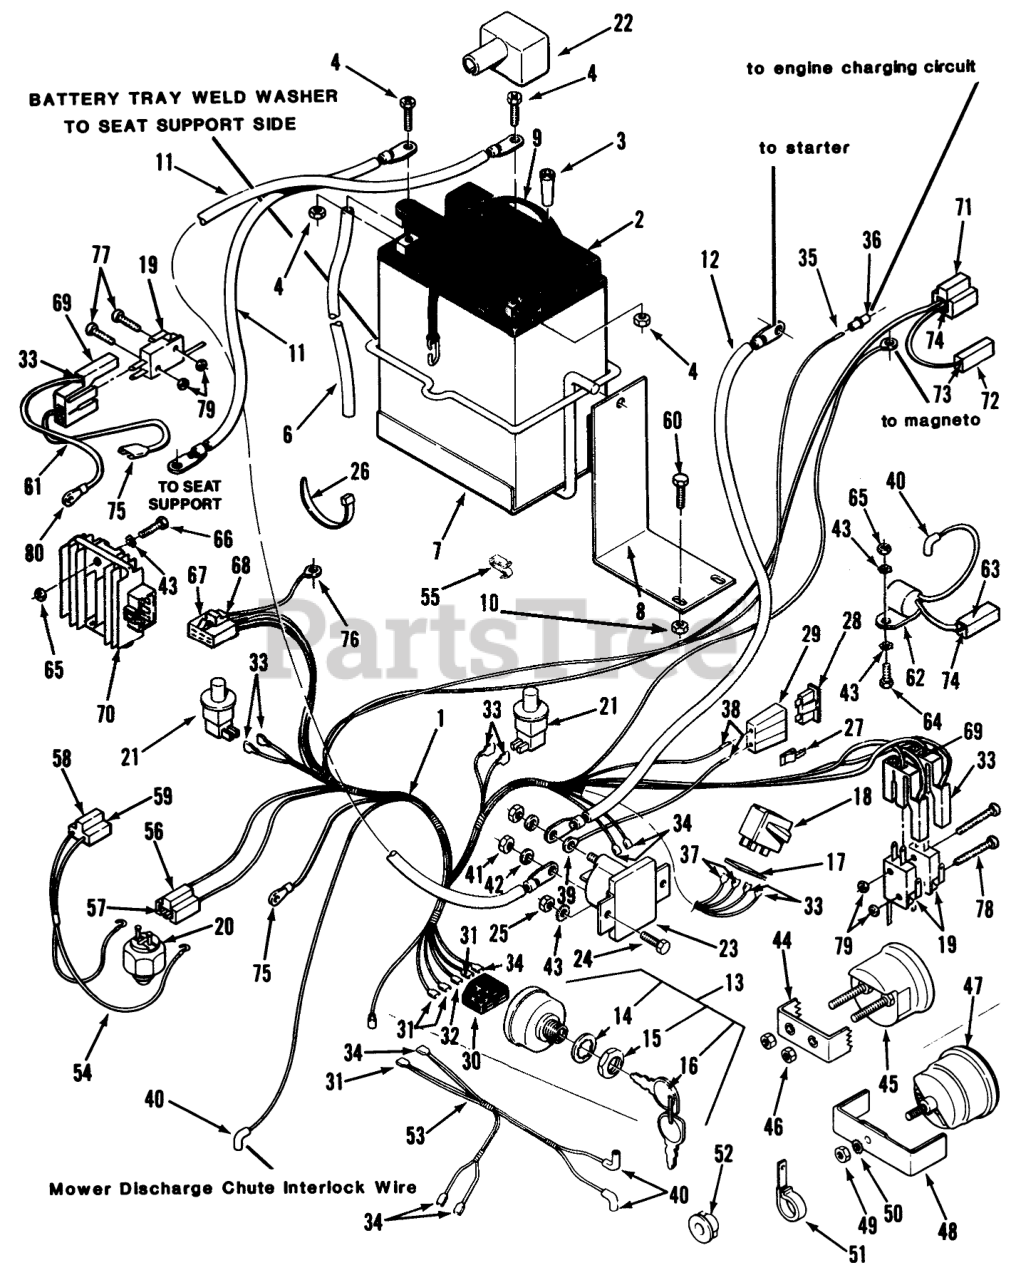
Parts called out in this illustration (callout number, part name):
1	WIRING HARNESS
2	BATTERY 120CCA
3	ADAPTER
4	ASSY BATTERY HDW
6	HOSE BATTERY DRAIN
7	BATTERY TRAY B
8	BRACKET B
9	STRAP
10	Nut
11	ASSY WIRE
12	WIRE ASM
13	Ignition Switch (includes items 14 & 15)
14	LOCKWASHER
16	Ignition Key
17	SHIELD-DIRT (DPDT)
18	PTO Interlock Switch w/item 17
19	SWITCH
20	SWITCH (N.C.-TRANS)
21	SWITCH (N.C.)
22	COVER-TERMINAL
23	Solenoid
24	Screw
25	Nut
26	PLASTIC TIE
28	FUSE-BLADE, 15 AMP
29	AUTO-FUSEBLOCK TERM
30	CONNECTOR-5 WAY-SERV
31	Terminal
32	Wire Terminal (Part of 1)
33	Wire Terminal (Part of 1)
34	Connector .250 x .032
35	Terminal
36	SOCKET HOUSING
37	Wire Terminal (Part of 1)
38	TERMINAL-FUSE
39	Wire Terminal (Part of 1)
40	Terminal Part of 5
41	Nut
42	Washer
43	LOCKWASHER
44	CLAMP MOUNTING
45	Voltmeter (includes items 44 & 46) 108-5 111-5, 111-6 & 112-C
46	HEX NUT 10-32 E.S.
47	Hourmeter (includes items 48, 49 50 & 51) 111-6 & 112-C
48	HOUR METER CLAMP
49	Hex Nut
50	Lockwasher
51	CLAMP
52	BUSHING-NYLON .75
53	Volt & Hourmeter Harness
54	ASSY WIRING HARNESS
55	SPEED CLIP
56	CONNECTOR BODY
57	Male Terminals (Part of 1)
58	CONNECTOR BODY B
59	TERMINAL-TAB RCPT
60	Bolt
61	WIRING-HARNESS
62	Interlock Module 112-C Only
63	CONNECTOR BODY ELECT
64	Screw
65	Nut
66	HHCS 1/4-20X1" WHIZ
67	6 Terminal Connector 112-C Only
68	Terminal 112-C Only
69	CONNECTOR BODY
70	Voltage Regulator 112-C Only
71	3-CONTACT LOCK-TYPE
72	CONNECTOR-5 WAY-SERV
73	Male Terminals (Part of 1)
74	TERMINAL-LONG MALE
75	Wire Terminal (Part of 1)
76	Ring Terminal 1/4 (Part of 1)
77	Screw
78	Screw 1/4-40 x 1-1/4 112-C Only
79	NUT HEX 4-40 ELAST
80	Piggy-Back Connector(Part of 6)
